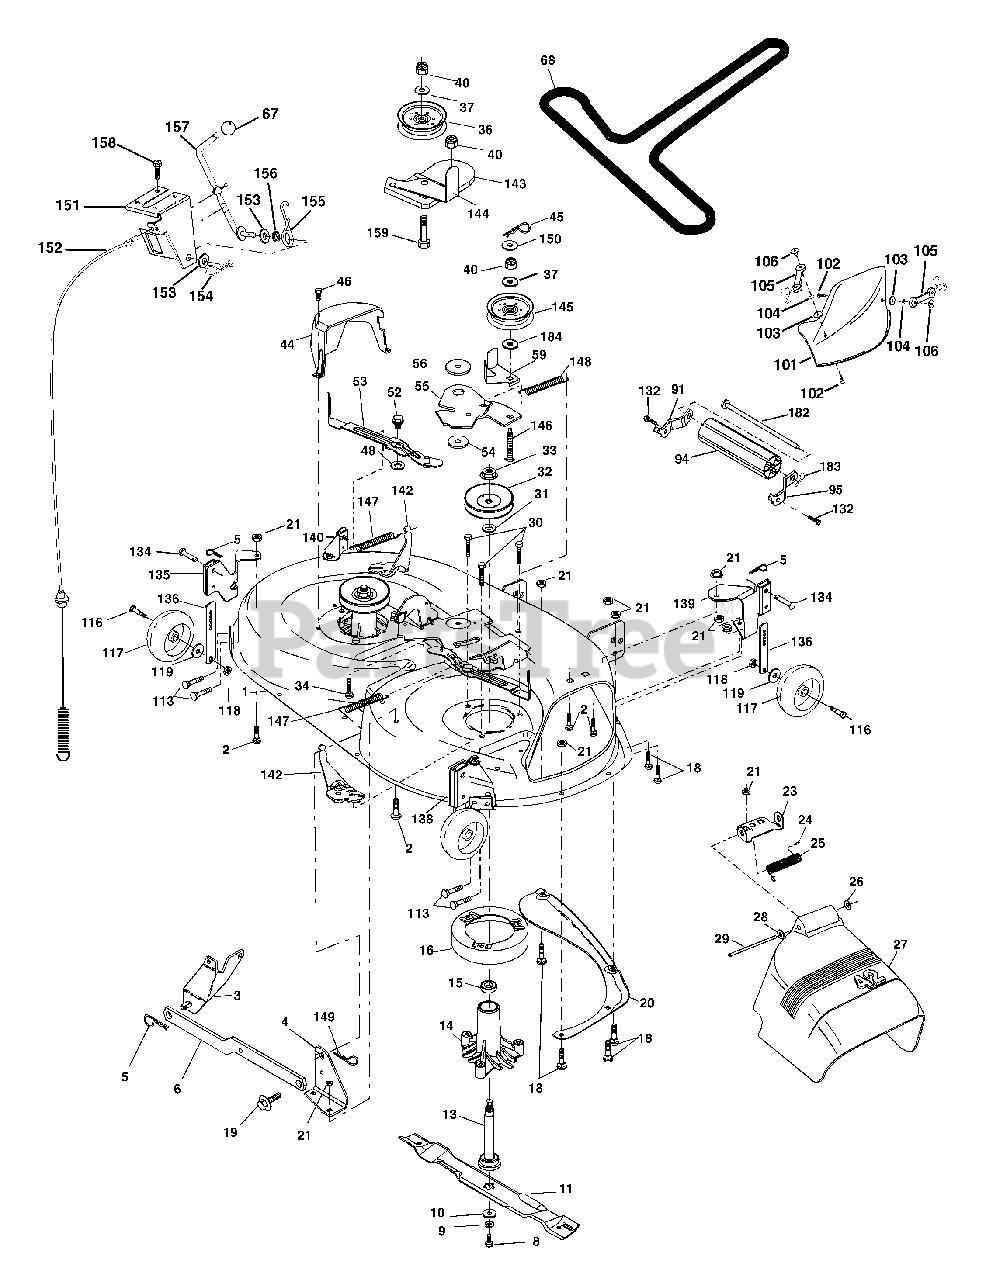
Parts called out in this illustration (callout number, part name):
1	Mower Deck Assembly, 42"
2	Bolt
3	Bracket Asm Fr. Sway Bar 3/42
4	Bracket Asm Deck 42" Sway Bar
5	Retainer Spring
6	Bar Sway Deck
8	Bolt 3/8-24 x 25 Grade 8 patched
9	Washer, Lock
10	Washer, Hardened
11	Blade, 42" Mulching Std
11	Blade, 42" Mulching Premium
11	Blade, 42" Hi-Lift
13	Shaft Assembly, Mandrel, Vented
14	Housing, Mandrel, Vented
15	Bearing, Ball, Mandrel
16	Stripper, Vented Mower Deck
18	Bolt, Carriage 5/16-18 x 5/8
19	Bolt, Shoulder
20	Baffle, Vortex
21	Nut
23	Bracket, Deflector Mower 42"
24	Cap, Sleeve 80 x 112 Blk Mower
25	Spring, Torsion, Deflector 2 52
26	Nut, Push Phos & Oil
27	Shield, Deflector 42" Blk
28	Washer 11/32 x 5/8 x 16 Gauge
29	Rod, Hinge 42" 6 75 W/G
30	Screw Thdrol Washer Head
31	Washer, Spacer Mower Vented
32	Pulley, Mandrel
33	Nut, Toplock Flange
34	Bolt
36	Pulley, Idler, Flat
37	Washer 13/32 x 13/16 x 16 Gauge
40	Nut
44	Guard, Mandrel, LH
45	Retainer
46	Screw, Thdrol 1/4-20 x 5/8 T
48	Washer, Hardened
52	Bolt, Shoulder 5/16-18 Unc
53	Arm Assembly, Pad, Brake
54	Washer, Hardened
55	Arm, Idler
56	Spacer, Retainer
59	Guard TUV Idler
67	Knob
68	V-Belt, 42" Mower
91	Bracket Noseroller LH
94	Roller Nose
95	Bracket Noseroller RH
101	Cover Mulching
102	Screw 10-24 x 5/8
103	Washer #10
104	Washer Lock #10
105	Latch Asm.
106	Nut Weld
113	Screw 5/16-18 x 3/4
116	Bolt Shoulder 3/8-16 x 3-5/8
117	Wheel Gauge
118	Nut 3/8-16
119	Washer 3/8 x 7/8 x 14 Ga.
132	Screw 3/8-16 x 3/4
134	Pin Head Rivet
135	Bracket Asm. LH Rear
136	Bar Adjusting
138	Bracket Asm. RH Rear
139	Bracket Asm. RH Front
140	Bracket Asm. LH Front
142	Arm Spring Brake Mower
143	Bracket Arm Idler 42"
144	Keeper Belt 42" Clutch Cable
145	Pulley Idler Flat
146	Bolt Carriage Idler
147	Spring Extension
148	Spring Return Idler
149	Retainer Spring Yellow
150	Washer 9/32 x 3/4 x 16 Ga.
151	Bracket Clutch Cable
152	Clutch Cable 42"
153	Washer Flat 3/8" Type B
154	Spring Retainer
155	Spring Retention LVR CLTCH CAB
156	Spacer Clutch Cable
157	Rod Clutch Cable 3/8"
158	Screw Hex Thd Cut 1/4-20 x 1/2
159	Bolt Rdhd Sqn 3/8-16 Unc x 1-3/4
182	Rod Roller Nose
183	Retainer Spring
184	Washer 13/32 x 7/8 x 10 Ga.
